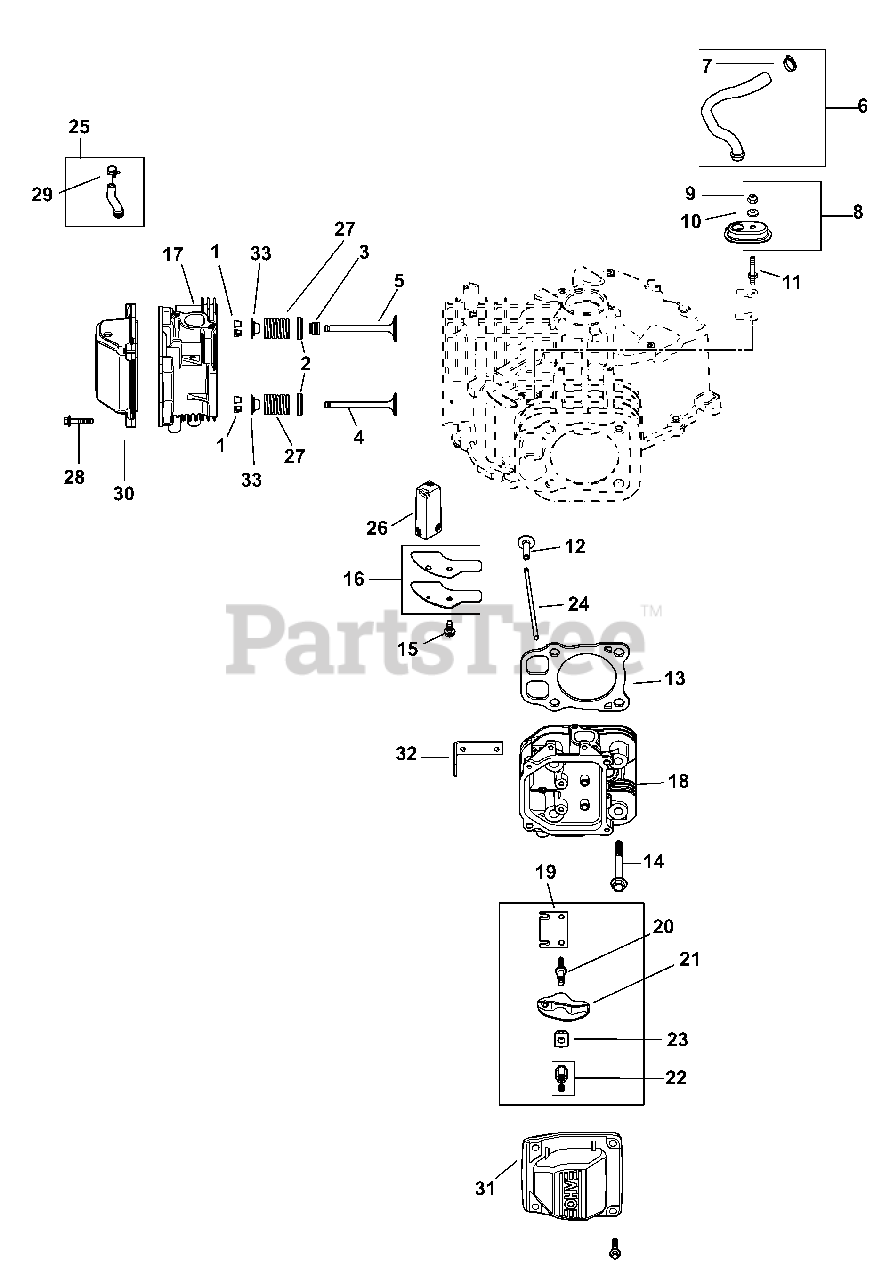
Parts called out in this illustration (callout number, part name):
1	Retainer Kit
2	Spring Retainer
3	Valve Stem Seal
4	Exhaust Valve (STD)
5	Intake Valve (STD)
6	Breather Hose Kit (Inc. #7)
7	Hose Clamp, 1/2
8	Housing Breather Kit (Inc. #9 & 10)
9	Lock Nut, M5 x 8
10	Sealing Washer
11	Breather Cover Stud
13	Cylinder Head Gasket Kit
14	Flange Screw, M10 x 1.5 x 90
15	Flange Screw, M6 x 1.0 x 16
16	Breather Cover
17	Cylinder Head Assembly Kit, #1
18	Cylinder Head Assembly Kit, #2
22	Hex Nut Assembly
23	Rocker Arm Pivot
25	Fuel Pump Hose Kit (Inc. #29)
26	Breather Filter
27	Valve Spring
28	Pan Head Screw
30	Rocker Cover
32	Lifting Strap
33	Valve Spring Cap
